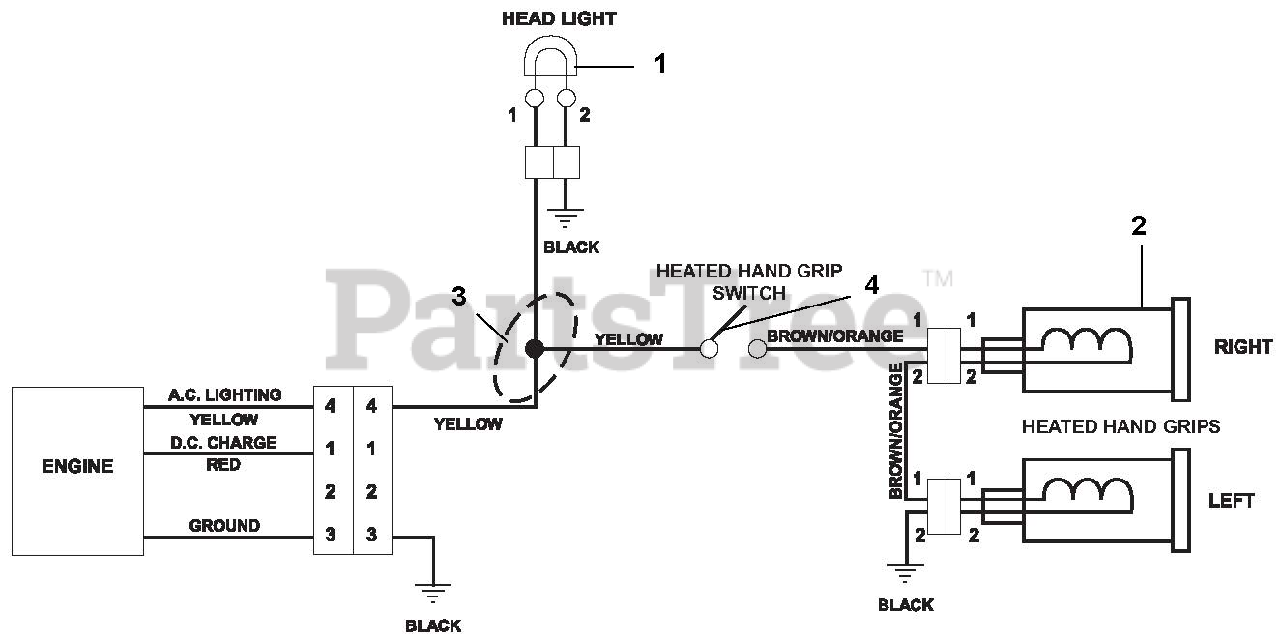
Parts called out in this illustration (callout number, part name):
1	HEADLIGHT ASY, HALO 20W 2SHOT
2	HEATED GRIP, MAGURA
3	HARNESS, LIGHT & WARMER
4	SWITCH, ON/OFF
